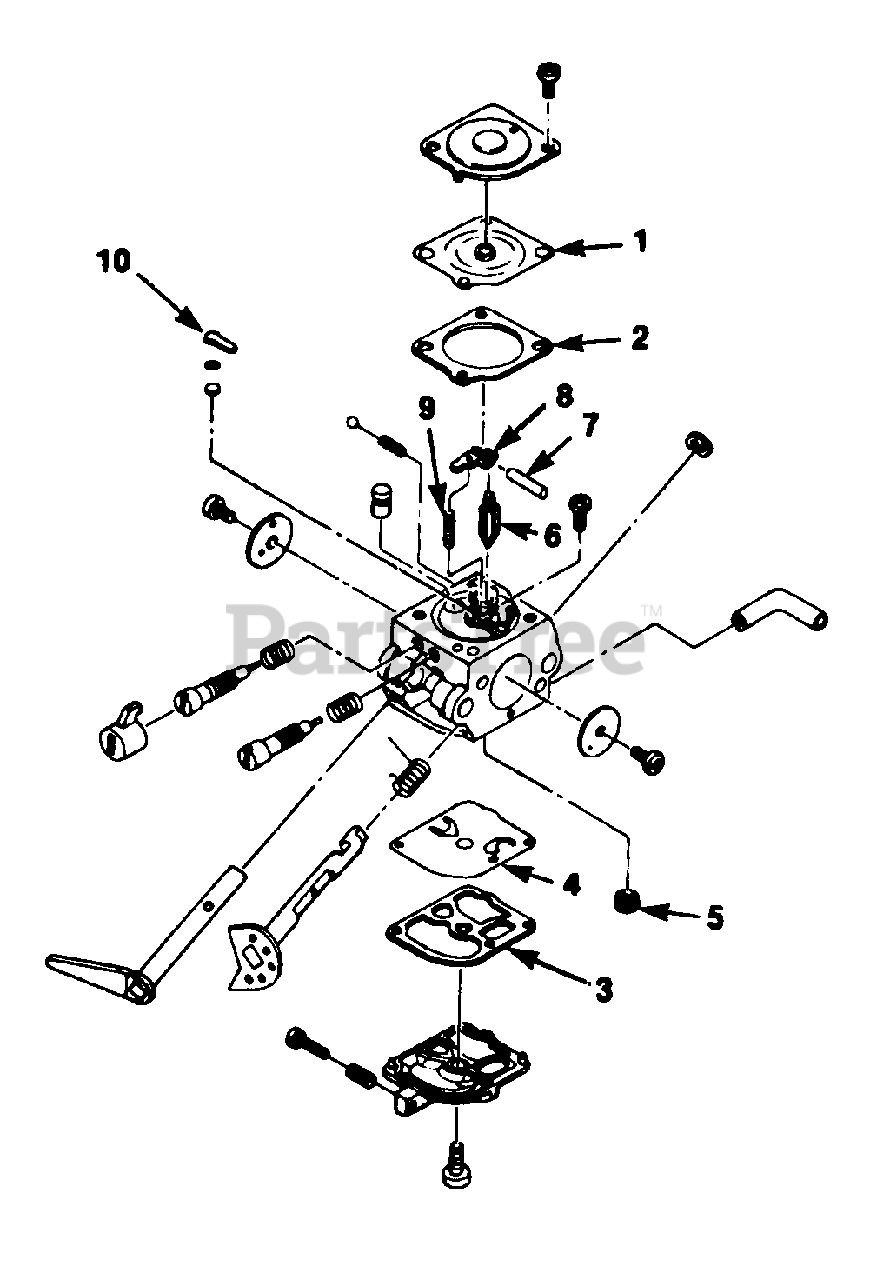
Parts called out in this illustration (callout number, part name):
1	Repair Kit
1	Gasket/Diaphragm Kit
2	Repair Kit
2	Gasket/Diaphragm Kit
3	Repair Kit
3	Gasket/Diaphragm Kit
4	Repair Kit
4	Gasket/Diaphragm Kit
5	Repair Kit
6	Repair Kit
7	Repair Kit
8	Repair Kit
9	Repair Kit
10	Repair Kit
